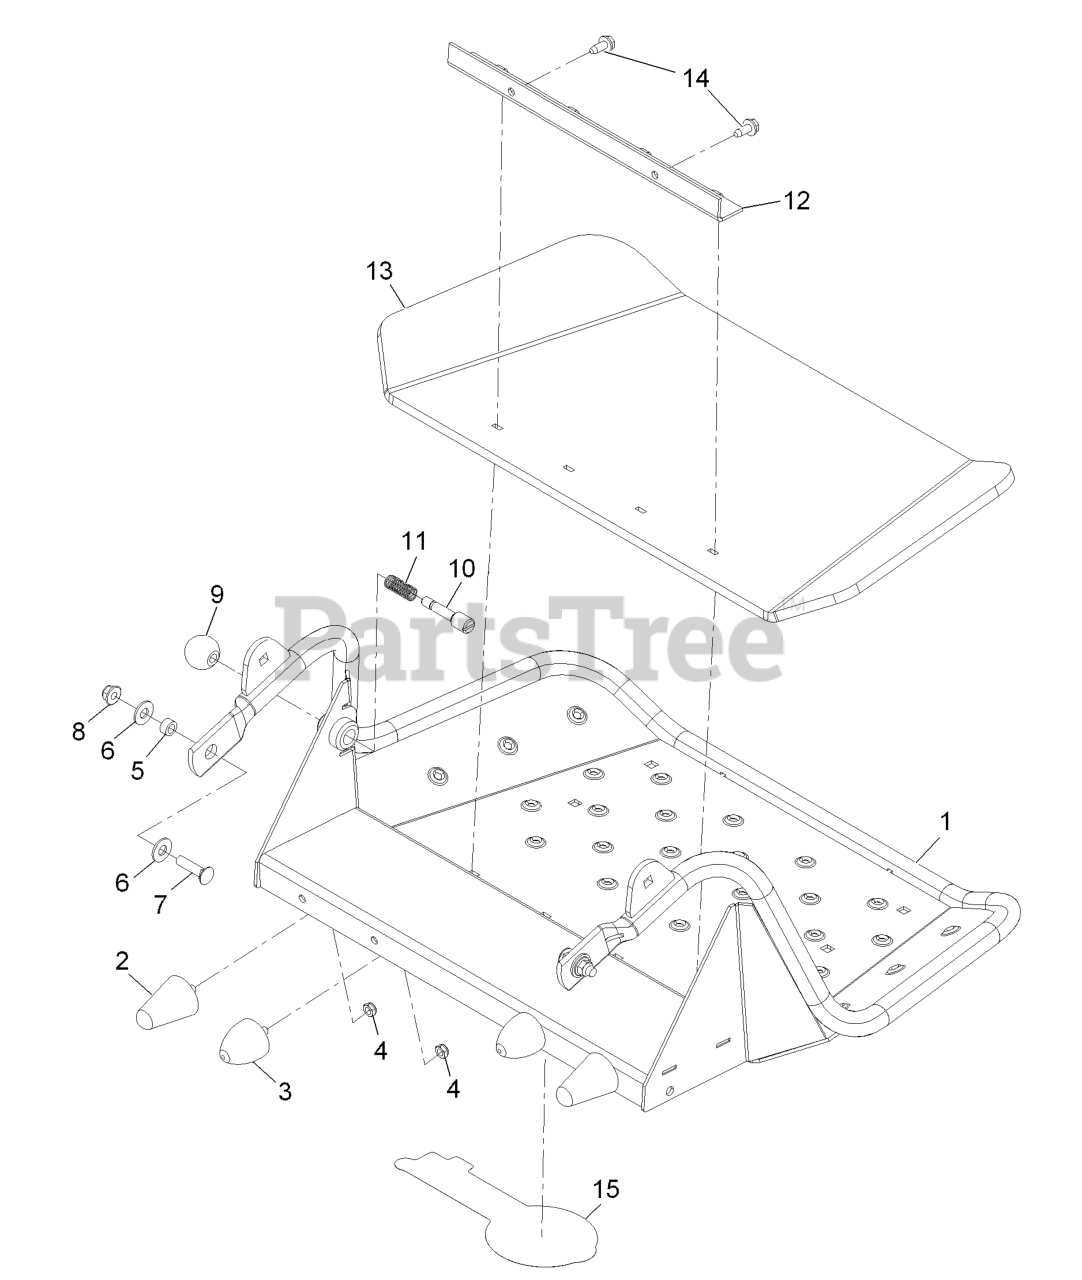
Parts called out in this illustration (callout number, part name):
1	PLATFORM ASM
2	BUMPER-RUBBER
3	BUMPER-RUBBER
4	NUT-LOCK, NI
5	SPACER
6	WASHER-FLAT
7	SCREW-CARR
8	NUT-HF, NI
9	KNOB-BALL
10	PIN-LATCH
12	CLAMP-SHIELD
14	Screw-HWH 5/16-18 X 3/4 Tf
15	DECAL, EXMARK LOGO
